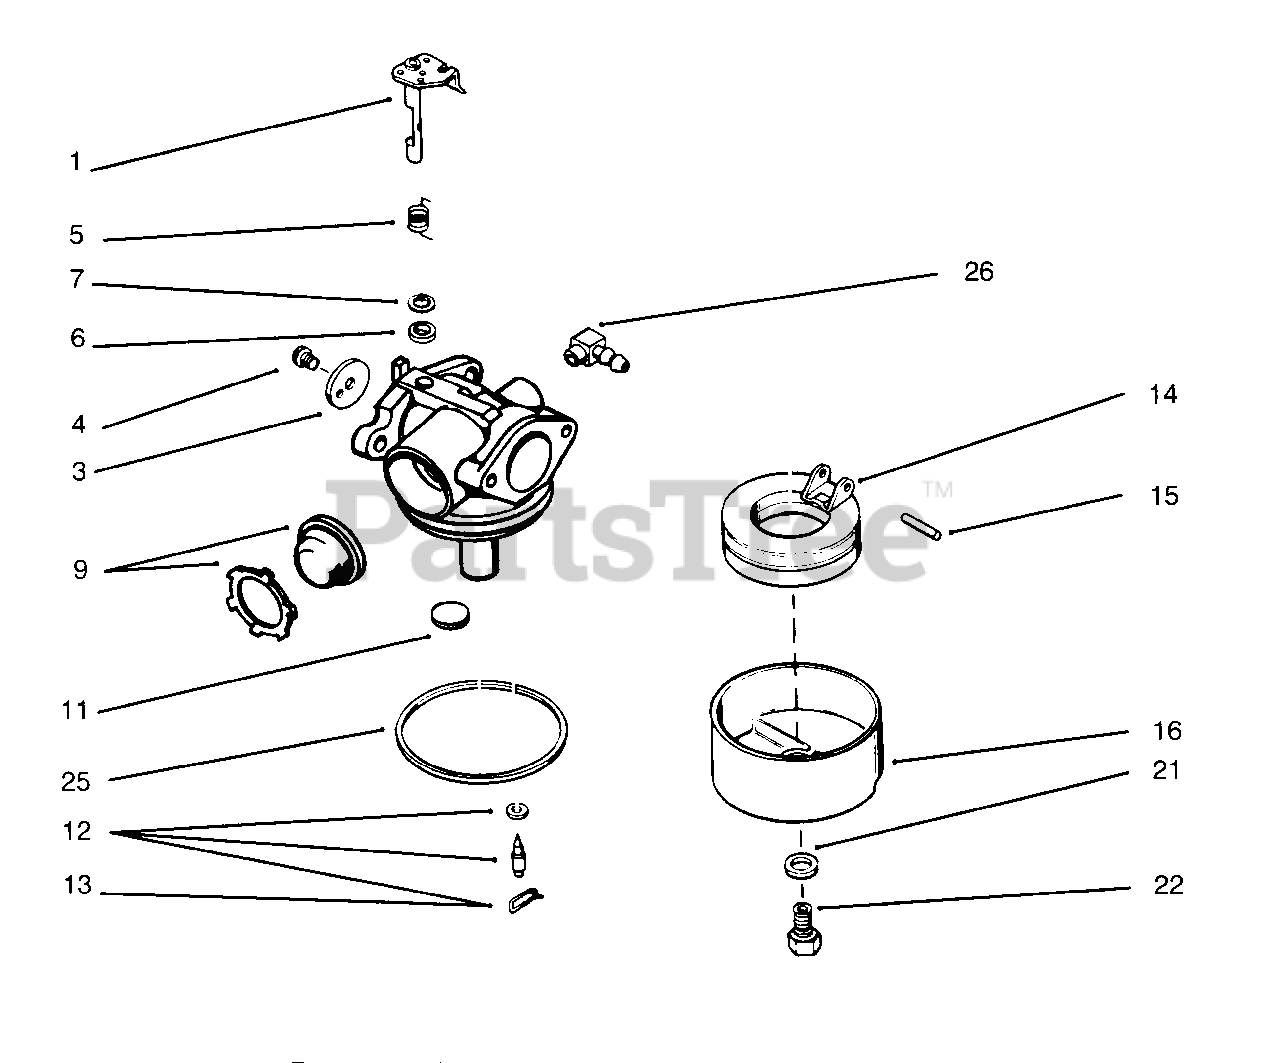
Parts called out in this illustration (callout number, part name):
1	Shaft And Lever Assembly
3	Shutter-Throttle
5	Spring-Return
6	Seal-Dust
7	Washer--Flat
9	Primer-Bulb & Retainer
12	Needle Seat & Clip Assembly (Incl. Ref. #13)
14	Float-Carburetor
15	Shaft-Float
16	Bowl-Float
21	Gasket-Bowl
22	Nut-Bowl
25	Gasket-Bowl
26	Fitting-Inlet
